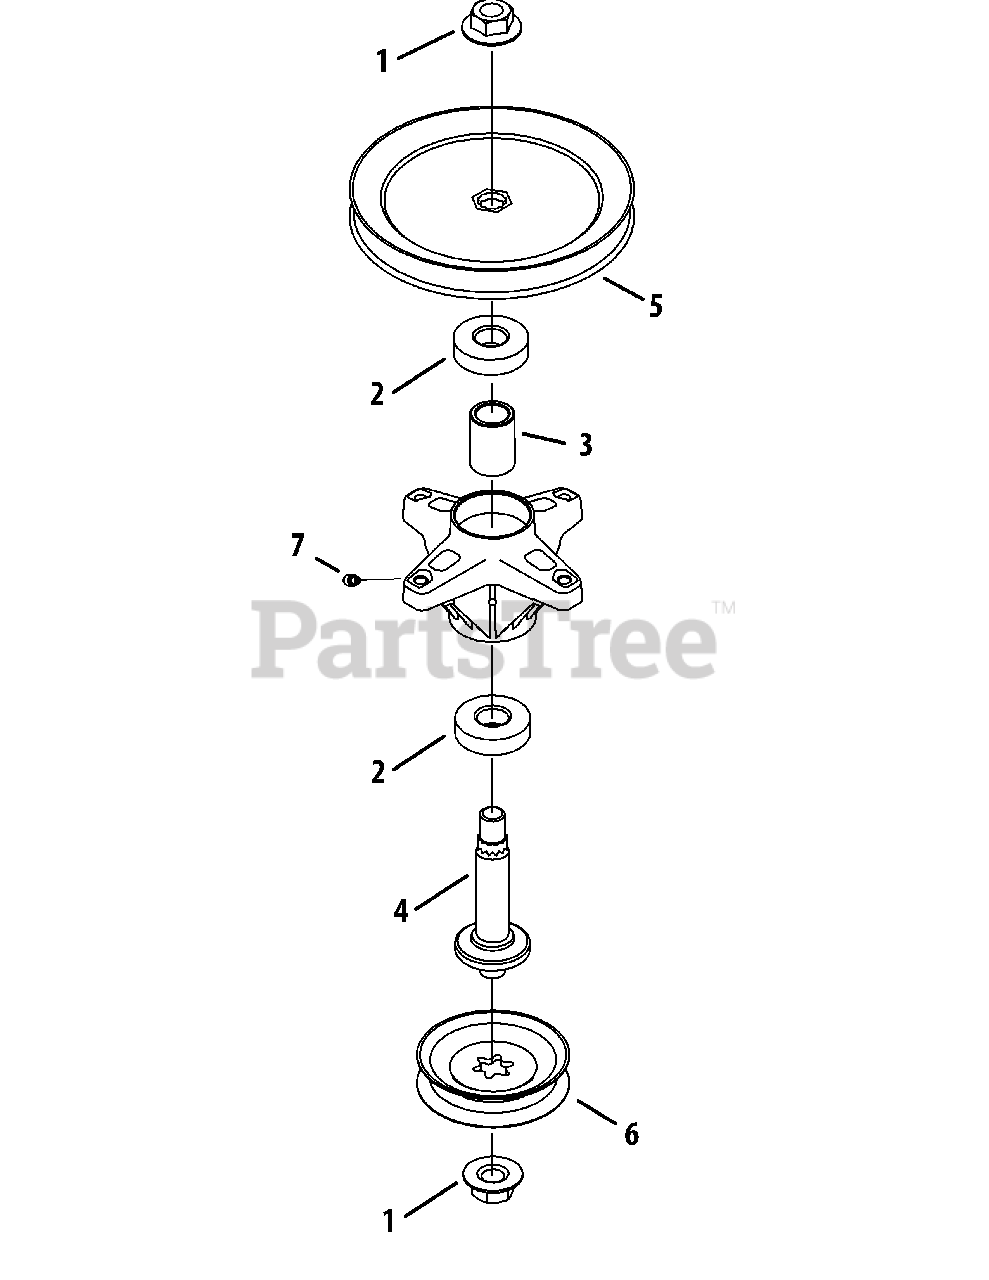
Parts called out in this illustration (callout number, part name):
1	Flange Nut 5/8-18
2	Ball Bearing
4	Spindle Shaft
5	Deck Pulley 7"
6	Pulley 3.75"
7	Lube Fitting, 3/16
